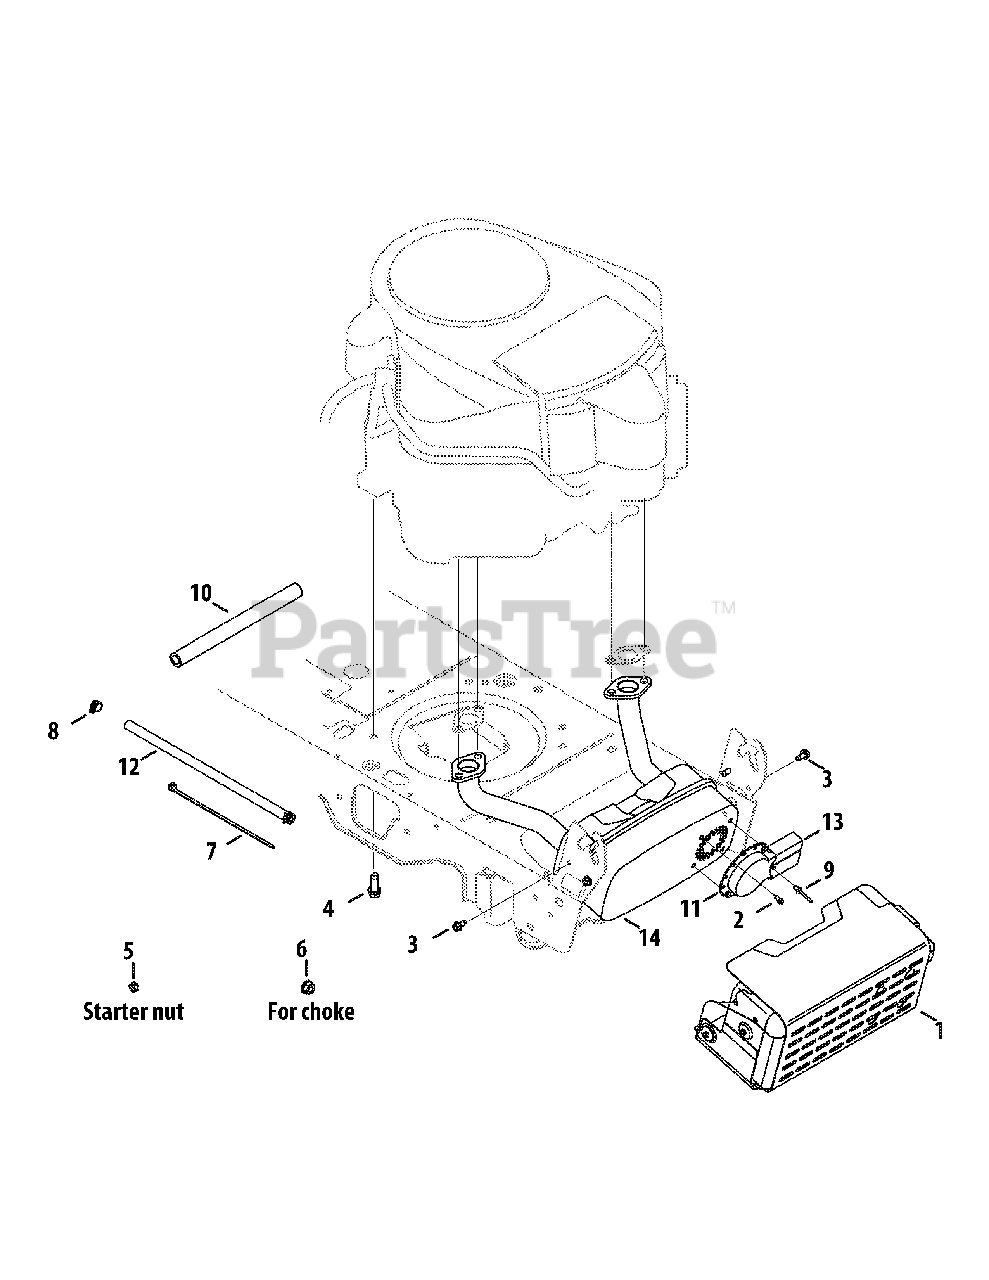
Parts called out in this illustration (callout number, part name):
1	Shield Ass’y, Muffler
2	Screw, Ab, #8-18, 0.500,
3	Screw, Self-tapping, 1/4-20, 0.500,
4	Screw, Self-tapping, 3/8-16, 1.25
5	Nut, Sems, 1/4-20
6	Nut, Flange Lock, 3/8-16
7	Cable, Tie, 3/16 x .05 x 7.4
8	Clamp, Hose, .490 Dia.
9	Rivet, Pop, .188 Dia x .300
10	Hose, Extension, Oil Drain
11	Deflector, Muffler
12	Hose, Fuel, Low Permeation, 1/4
13	Deflector, Muffler, Long
14	Muffler, Kawasaki Twin
